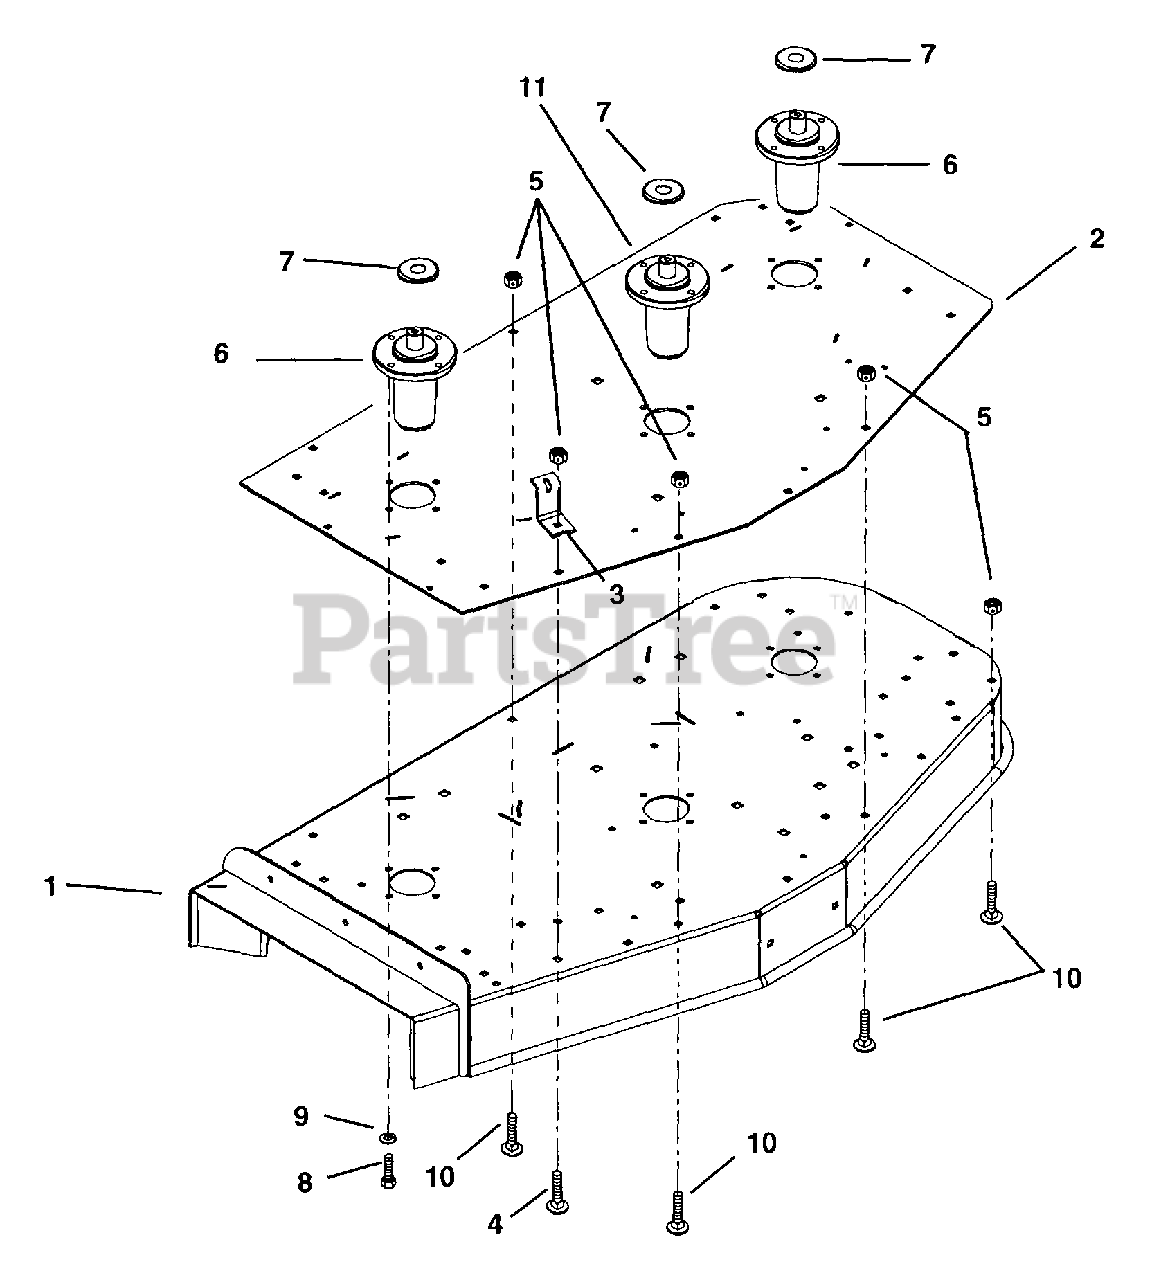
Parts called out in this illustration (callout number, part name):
1	Weldment, 50" Deck (Side Discharge)
2	Plate, 50" Reinforcement
3	Anchor, Spring
4	Bolt-Round Head Square Neck .38-16 x 1.25 Grade 2
5	Nut-Locking-Nylon .38-16
6	Assembly, Spindle L-Hub
7	Slinger-Dust
8	Bolt-Hex .38-16 x 1.00 Grade 5
9	Washer-Locking .38 x .094
10	Bolt-Round Head Square Neck .38-16 x 1.00 Grade 2
11	Assembly, Spindle
